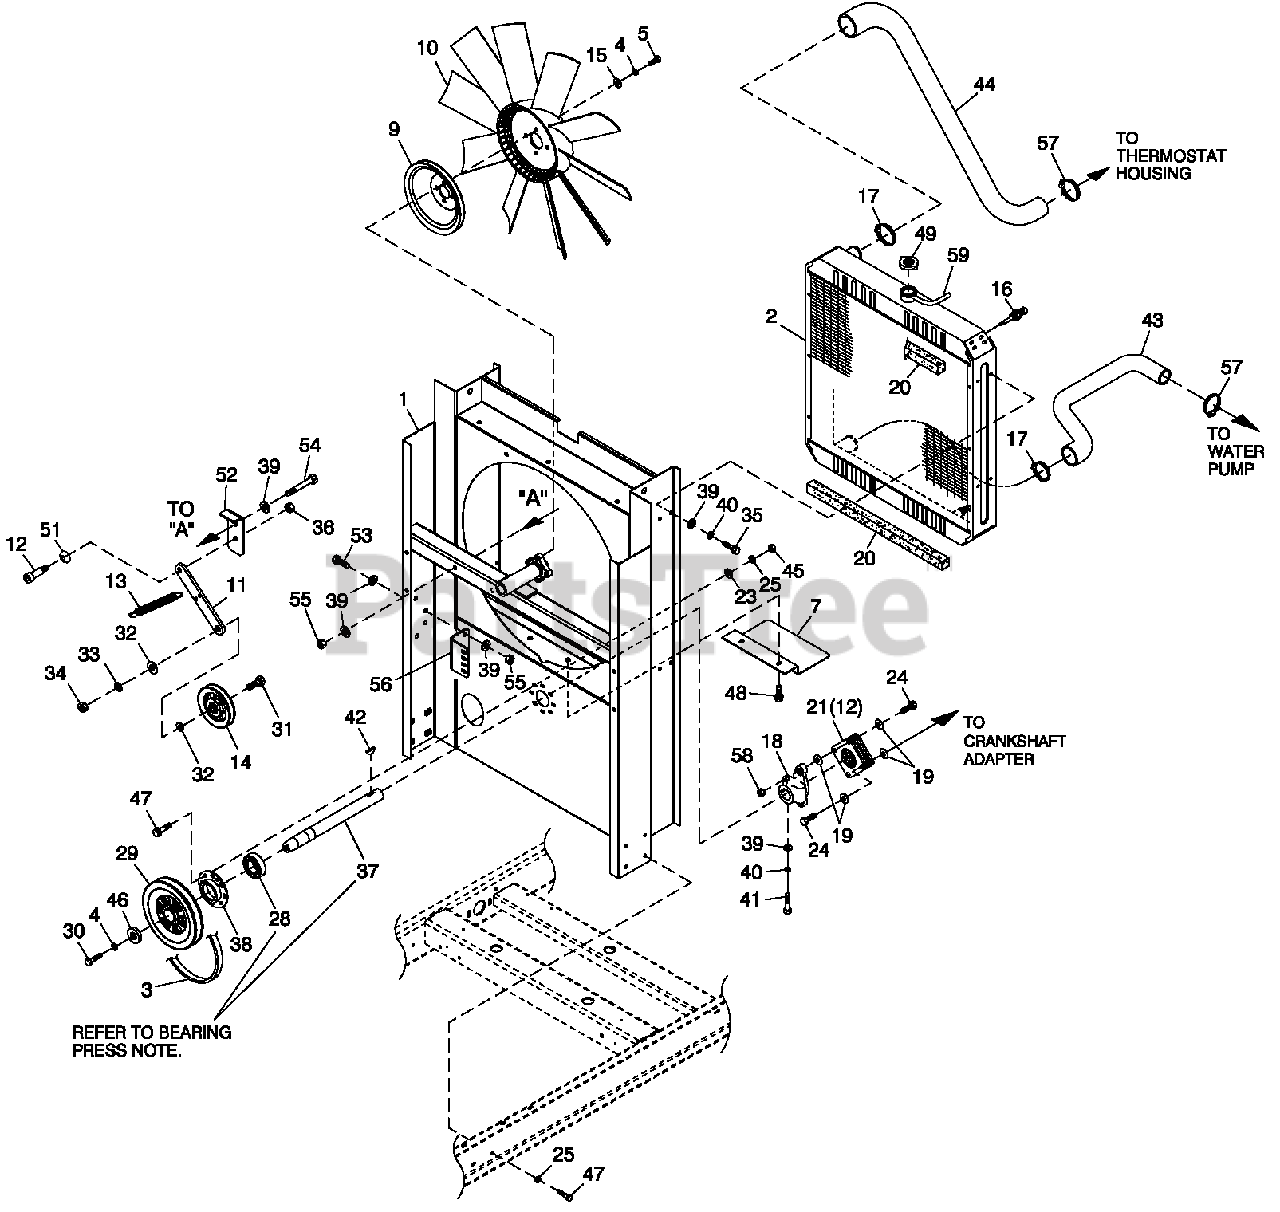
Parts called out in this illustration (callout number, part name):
1	WELDMENT RADIATOR SUPPORT C2
2	RADIATOR 598 X 568 X 49 CPL RH
3	V- BELT A58 (60IN O.C.) DDC S60
4	WASHER LOCK M10
5	SCREW HHC M10 -1 .5 X 30 G10.9
6	HOSE 2 "ID X 3.0"L G
7	SHIELD RADIATOR C4
8	TANK COOLANT RECOVERY
9	PULLEY FAN V-GROOVE 9"
10	FAN COOL 22" DIA 10 BLADE LH
11	FLAT TENSIONER ARM
12	SHOULDER BOLT 3/8 X 1/2"
13	SPRING TENSION CPL
14	PULLEY V - BELT 4" FLANGED
15	WASH ER FLAT 3/8-M10 ZINC
16	PROBE COOLANT LEVEL 3/8 NPTF
17	CLAMP HOSE #28 1.32-2.25
18	HUB FLEX PLATE
19	W ASH ER FLEX (THIN)
20	TAPE FOAM 1 X 1 (26.75" LG)
21	DISK FLEX
22	BRACKET COOLANT TANK
23	WASHER FLAT 1/4-M6 ZINC
24	SCREW HHC 5 /16 -24 X 1.124
25	W ASH ER LOC K M6-1/4
26	TANK COOLANT RECOVERY
27	CLAMP HOSE BAND 1/4
28	BEARING #6205 2NSE C3 E SRI2 S
29	PULLEY 7.5" DIA MACHINED
30	SCREW HHC M10 -1.5 X 30 G8.8
31	SCREW HHC 1 /2 -1 3 X 2 " G8
32	WASHER FLAT 1/2 ZINC
33	WASHER LOC K 1/2
34	NUT HEX 1/2-13 STEEL
35	SCREW HHFC M8-1.25 X 20 W/M6
36	NUT HEX LO C K 5/16-18 NY INS SS
37	SHAFT FAN DRIVE
38	RETAINER BEARING
39	WASH ER FLAT 5/16-M8 ZINC
40	WASH ER LOC K M8-5/16
41	SCREW HHC M8-1.25 X 35 G8.8
42	KEY WOODRUFF 4 X 19D
43	HOSE LOWER RADIATOR G2
44	HOSE UPPER RADIATOR G2
45	NUT HEX M6 X 1.0 G8 YEL CHR
46	SPACER .5 X 1.5 X .25 STL/ZINC
47	SCREW HHFC M6 -1 .0X 20 G8.8
48	SCREW THF M6-1 X 16 N W A Z/JS
49	CAP RADIATOR 13 PSI
50	BRACKET COOLANT TANK
51	WASH ER B ELLEVILLE .75X.38X.028
52	TENSIONER ARM SUPPORT BENT 90
53	SCREW HHC M8-1.2 5 X 2 0 C8.8
54	SCREW HHC M8-1.2 5 X 7 5 C8.8
55	NUT HEX LOCK M8-1.25 NY INS
56	BRACKET TENSIONER SPRING
57	CLAMP HOSE #24 B 1.06-2.00
58	NUT HEX LO C K 5/16-24 NY INS
59	HOSE 9/32 ID (36" LG)
60	CAC 504W X 152H X 50D 2.4L G2
61	CLAMP CNST TENSION 1.75-2.625
62	HOSE 2 "ID X 3.0 "L G
63	TUBE CAC IN
64	TUBE CAC OUT G 2T U R B O
65	SCREW THF M6-1 X 30 N WA DELTA
